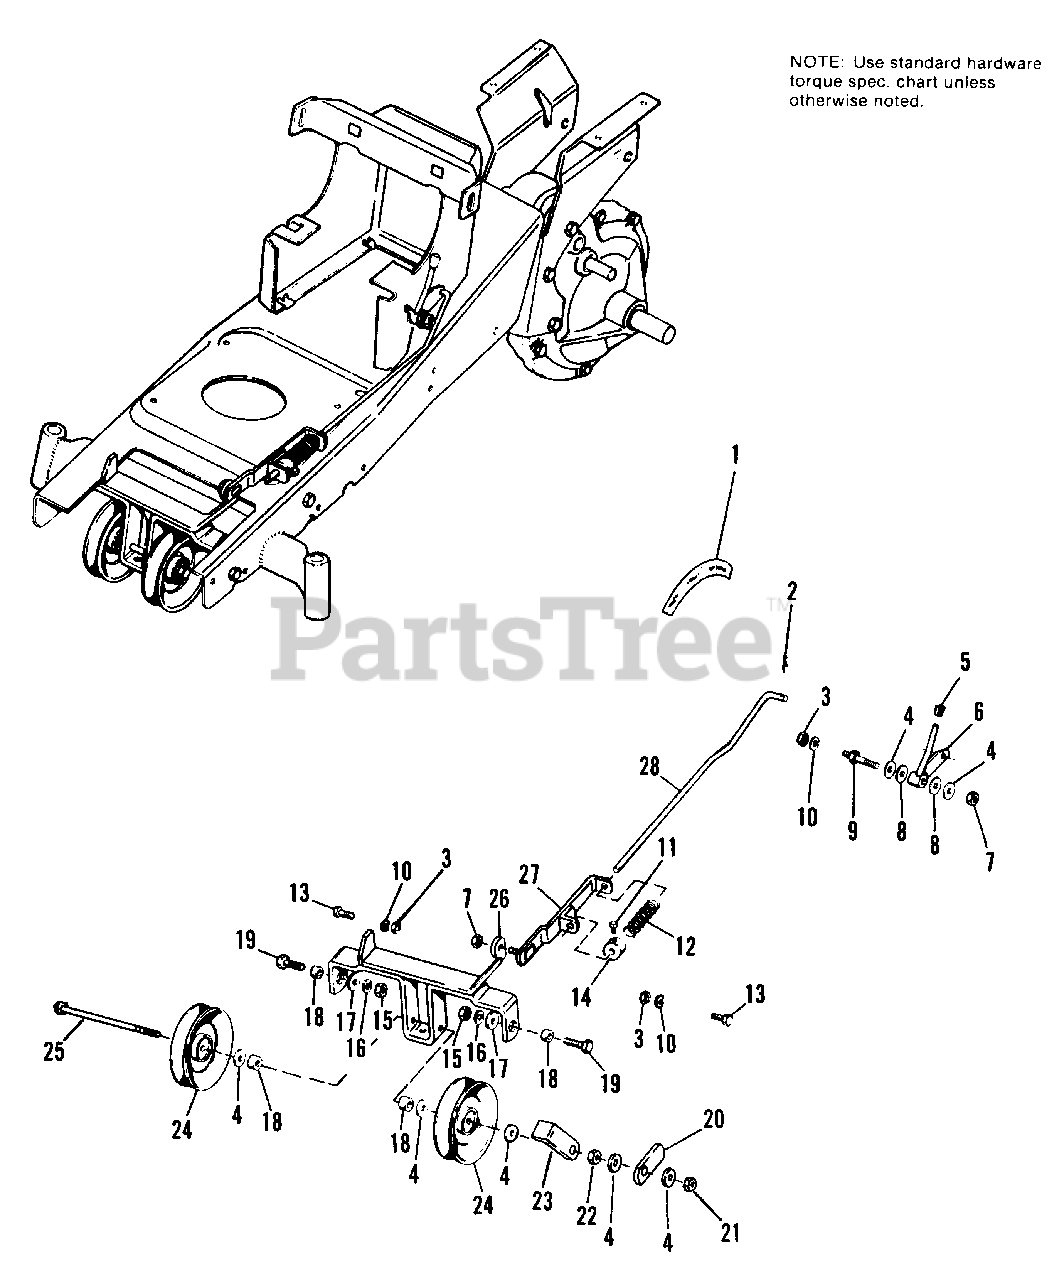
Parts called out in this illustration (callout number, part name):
1	DECAL, P.T.O.
2	PIN, Cotter, 3/32 x 5/8
3	NUT, Hex, Full, 5/16-18
4	WASHER, Plain, 5/16
6	HANDLE ASSY., P.T.O.
7	LOCKNUT, Hex, 5/16-18
8	WASHER, Nylon
9	STUD (990486 & 990542 Only)
10	LOCKWASHER, 5/16
11	SETSCREW, 1/4-20 x 3/8
12	SPRING (990645, 990646, 990778 & 990779 Only)
13	CAPSCREW, Hex Hd., 5/16-18 x 3/4
14	COLLAR, Set
15	NUT, Hex, Full, 3/8-16
16	LOCKWASHER, 3/8
17	WASHER, Plain, 3/8
17	STOP, Pulley
19	CAPSCREW, Hex Hd., 3/8-16 x 1
20	STOP, Pulley (990778 & 990779 Only)
21	LOCKNUT, Hex, 3/8-16
22	LOCKNUT, Hex, Jam, 3/8-16
23	STOP, Belt
24	PULLEY, Idler
24	CLEVIS ASSY.
25	CAPSCREW, Hex Hd., 3/8-16 x 4-1/2
26	CLEVIS ASSY. (990778 & 990779 Only)
27	GUIDE ASSY., Rod (990778 & 990779 Only)
27	GUIDE ASSY., Rod
28	ROD, Clutch, P.T.O.
